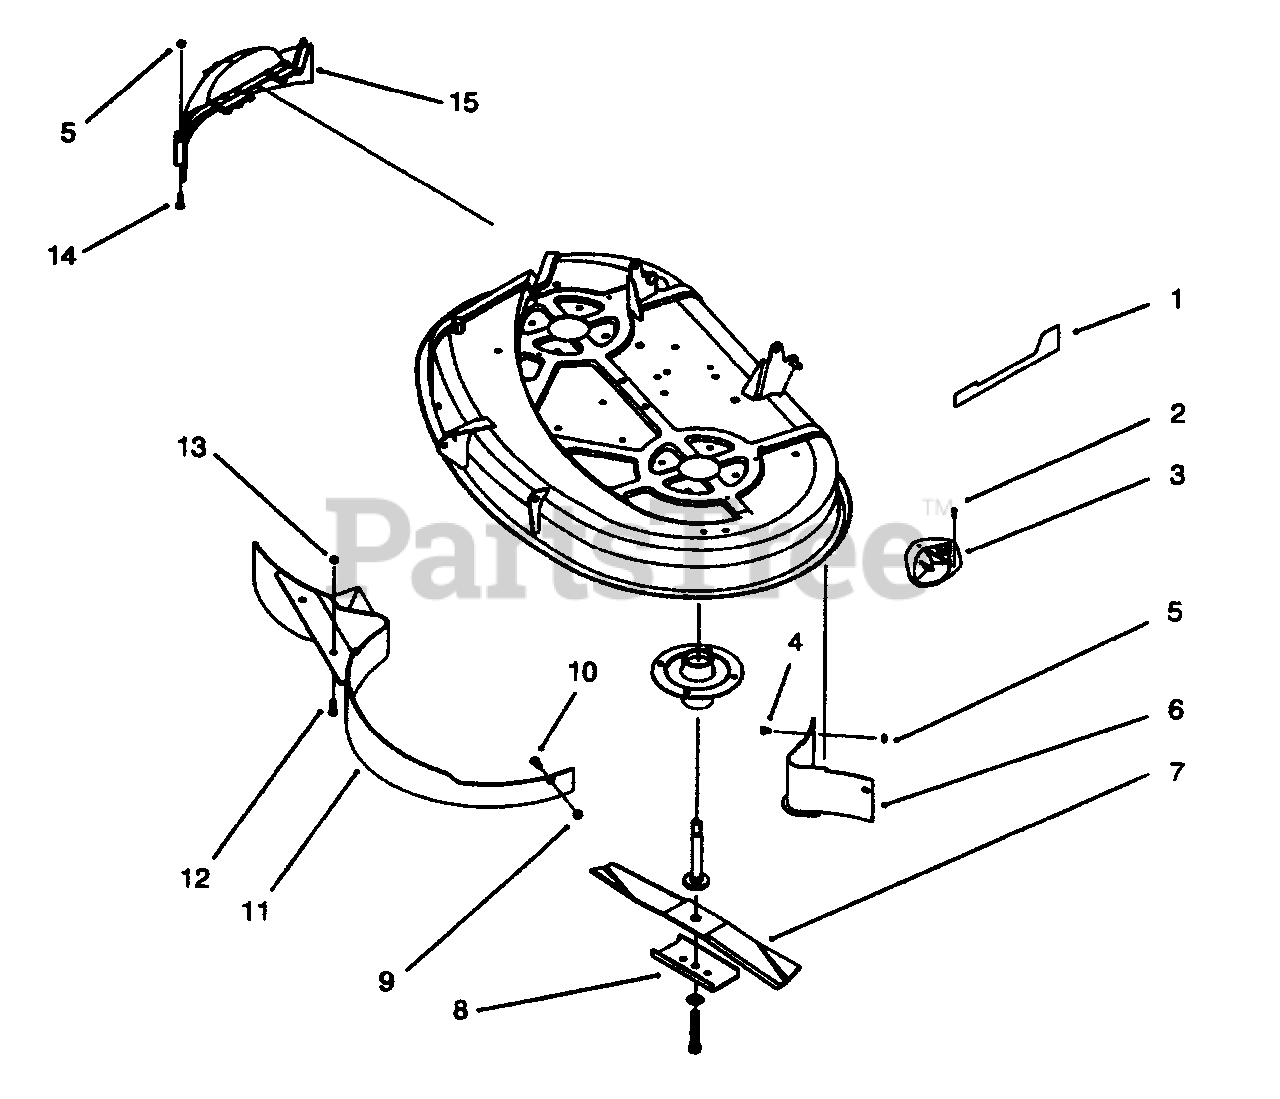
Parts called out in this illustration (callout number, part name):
1	Decal-38" Recycler
2	Screw-Plastite
3	Kicker-Plate
4	Screw-Hex Hd Cap
5	Nut-Lock
6	Baffle-Deck Rear
7	Blade-38" Recycler
8	Stiffener-Blade
9	Nut-Lock
10	Bolt-Carriage
11	Baffle-38" Recycler
12	Screw-Hex Hd. Cap
13	Nut-Lock
14	Screw-Hex Hd. Cap
15	Cover-38" Recycler
